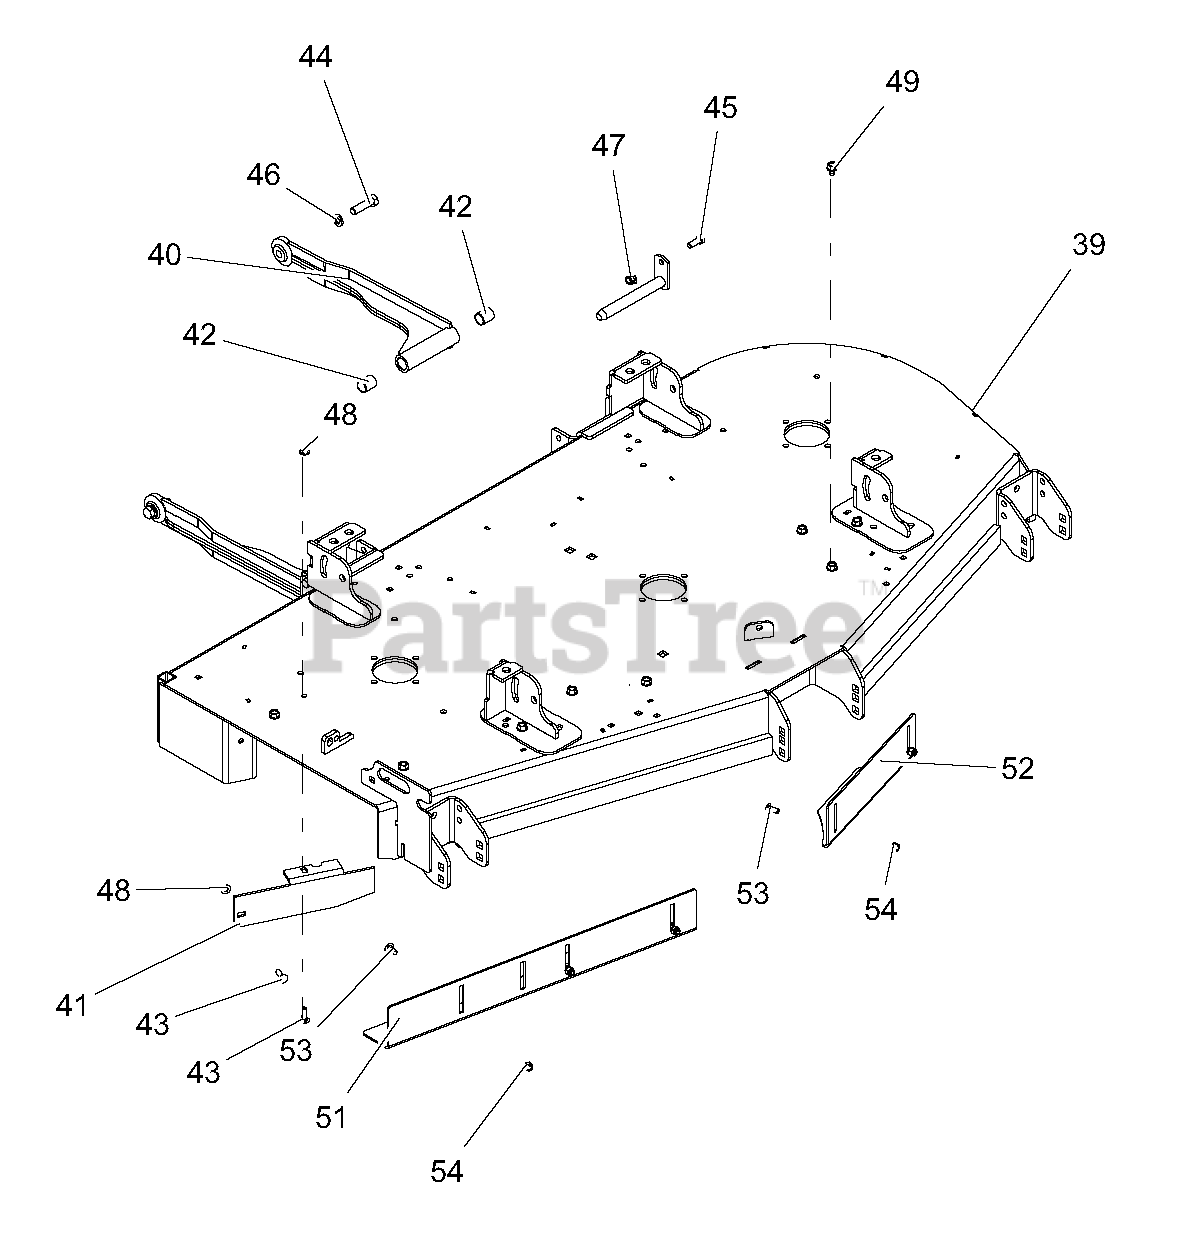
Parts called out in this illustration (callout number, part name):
39	WLDMT, 60" SIDE DISCH DECK
40	WMT, DECK STABILIZER ARM-BLACK
41	BAFFLE, 60" DISCHARGE
42	BRG, .75 X .875 X 1.00
43	BLT-RDHDSQSHNK .31-18X1.00 G5 Y
44	BLT-HEX .50-13X1.75 GR5 YWZC
45	BLT-HEX .38-16X1.00 GR5 YWZC
46	WSHR-LK .50X.125 REG YWZC
47	NUT-LK-NYL-FLG .38-16 YWZC
48	NUT-LK-NYL-FLG .31-18 YWZC
49	SCR-TAP .38-16X.50 HWH TR YWZ
51	BAFFLE, 60" RH VACUUM
52	BAFFLE, 60" LH VACUUM
53	BLT-RDHDSQNK .31-18X.75 G5 YWZC
54	NUT-LK-NYL .312-18 YWZC
